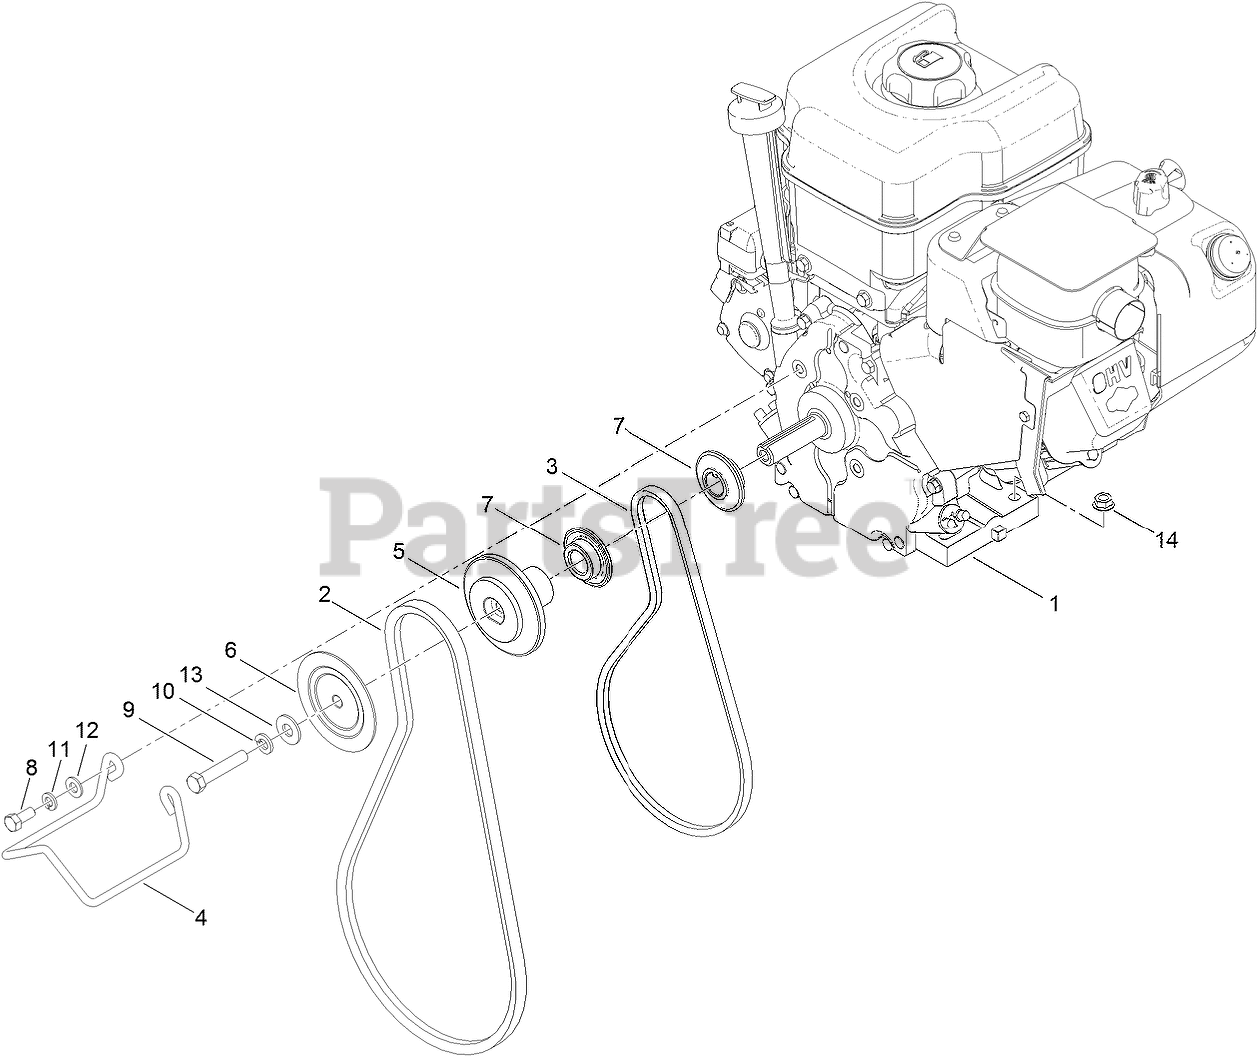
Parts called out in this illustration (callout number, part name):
2	BELT-V
3	BELT-V
4	GUIDE-BELT
5	PULLEY-AUGER, REAR
6	PULLEY-AUGER, FRONT
7	PULLEY-TRACTION
8	SCREW-HH
9	SCREW-HH
10	WASHER-LOCK
11	WASHER-LOCK
12	WASHER-PLAIN
13	WASHER-FLAT
14	NUT-HF
